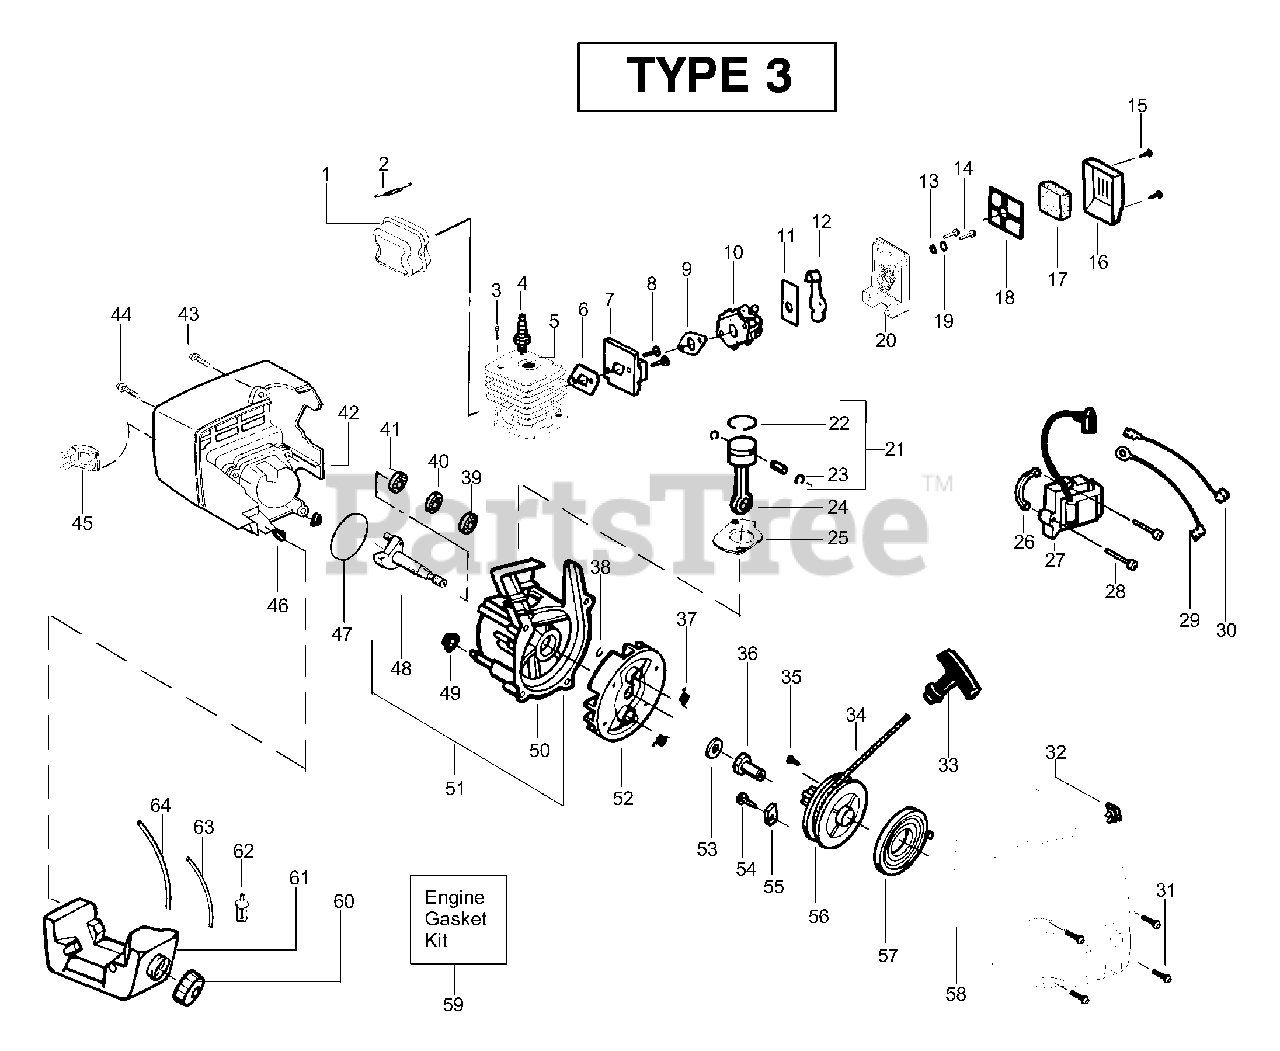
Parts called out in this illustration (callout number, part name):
1	Kit - Muffler
2	Muffler Spring
3	Screw-Cylinder
4	Spark Plug (RCJ-6Y)
5	Kit - Cylinder
6	Gasket-Cyl/Carb. (kit)
7	Adaptor-carb.
9	Gasket-Carb. (kit)
10	Kit-Carb. (WA226)
11	Plate-Choke Mounting
12	Lever-Choke
16	Cover-Air Box
17	Foam-Air Filter
18	Plate-Air Filter Support
19	Spacer-Choke
21	Kit - Piston
22	Piston Ring
23	Retainer-Piston Pin
24	Assy-Connecting Rod
25	Gasket-Cylinder (kit)
26	Spacer-Module
27	Ignition Module
29	Assy-Ground Wire
30	Assy-Leadwire
31	Screw
32	Kit-Switch
33	Handle-Starter
34	Kit - Rope
36	Coupling-Drive
37	Spring-Starter Dog
38	Retain. Ring-C'shaft
39	Bearing-Outer
40	Seal-C'case
41	Bearing-Inner
44	Screw
45	Guard-Muffler
46	Isolator-Shroud
47	O-Ring-C'case (kit)
48	Assy-Crankshaft
49	Isolator-Crankcase
50	Assy-Crankcase
51	Assy-C'case & C'shaft
52	Assy-Flywheel
53	Washer-Flat
55	Retainer-Can
56	Kit-Starter Pulley
57	Spring-Starter
58	Assy-Fan Housing
59	Kit-Engine Gasket
60	Assy-Fuel Cap
61	Assy-Fuel Tank
62	Assy-Fuel Pickup
63	Kit-Fuel Line
64	Kit-Fuel Line
